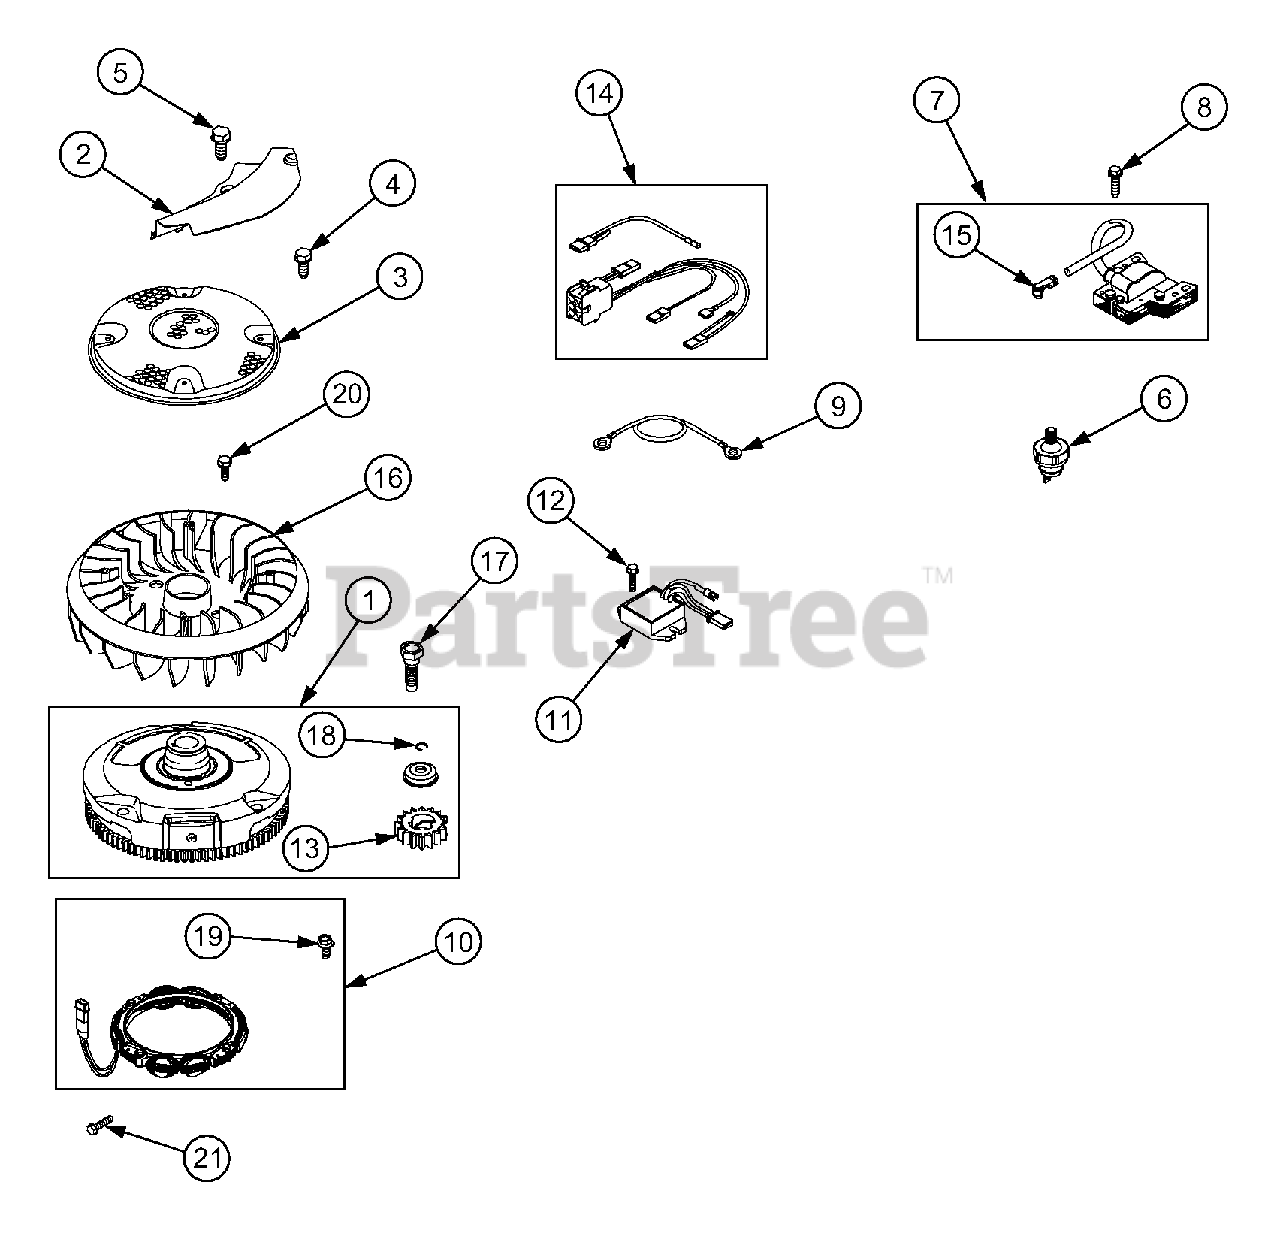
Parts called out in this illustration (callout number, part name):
2	Guard, Flywheel
3	Screen, Rotating
4	Screw (Rotating Screen)
5	Screw (Flywheel Guard)
6	Switch, Oil Pressure
7	Armature, Magneto
8	Screw (Armature)
9	Wire, Stop
10	Alternator
11	Regulator
12	Screw (Regulator)
13	Gear, Pinion
14	Harness, Wiring
15	Terminal, Spark Plug
16	Fan, Flywheel
17	Screw (Flywheel)
18	Ring, Retaining
19	Kit, Screw/Washer
20	Screw (Flywheel Fan)
21	Screw (Alternator)
